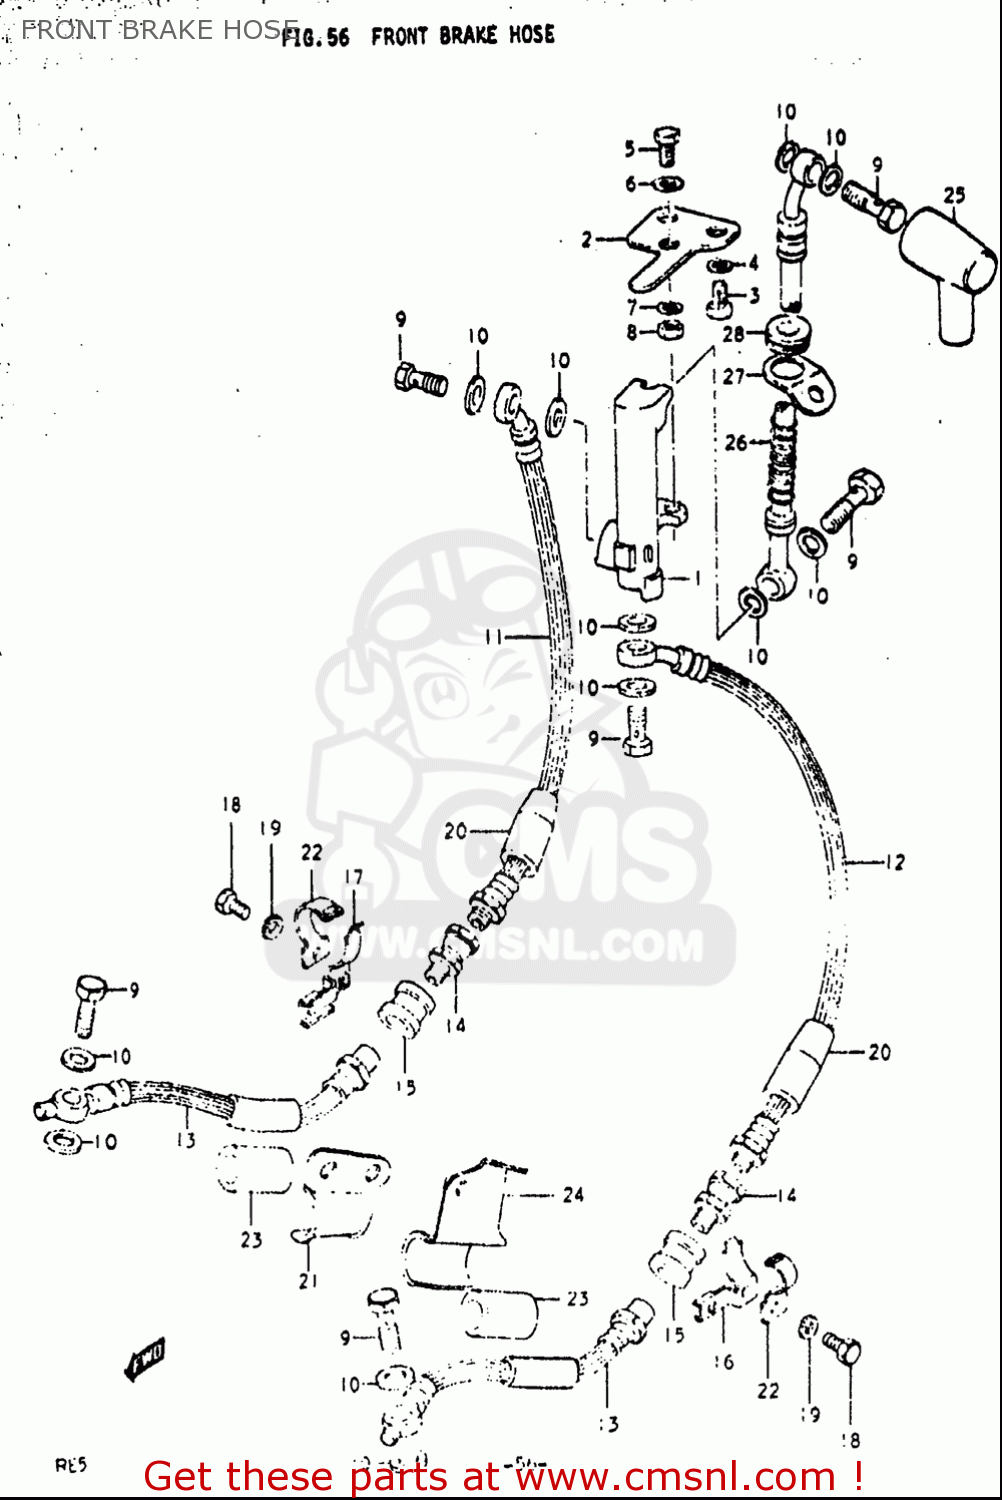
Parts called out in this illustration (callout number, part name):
3	BOLT
4	WASHER,LOCK
5	BOLT
6	WASHER
7	WASHER,LOCK
8	NUT
9	BOLT UNION
10	WASHER(10X15X1.5)
13	HOSE,BRAKE NO.3
15	BUSH
18	SCREW(6X12)
19	WASHER,LOCK
23	CUSHION
25	BOOT,MASTER CYLINDER
26	HOSE,BRAKE NO.1
28	GROMMET
